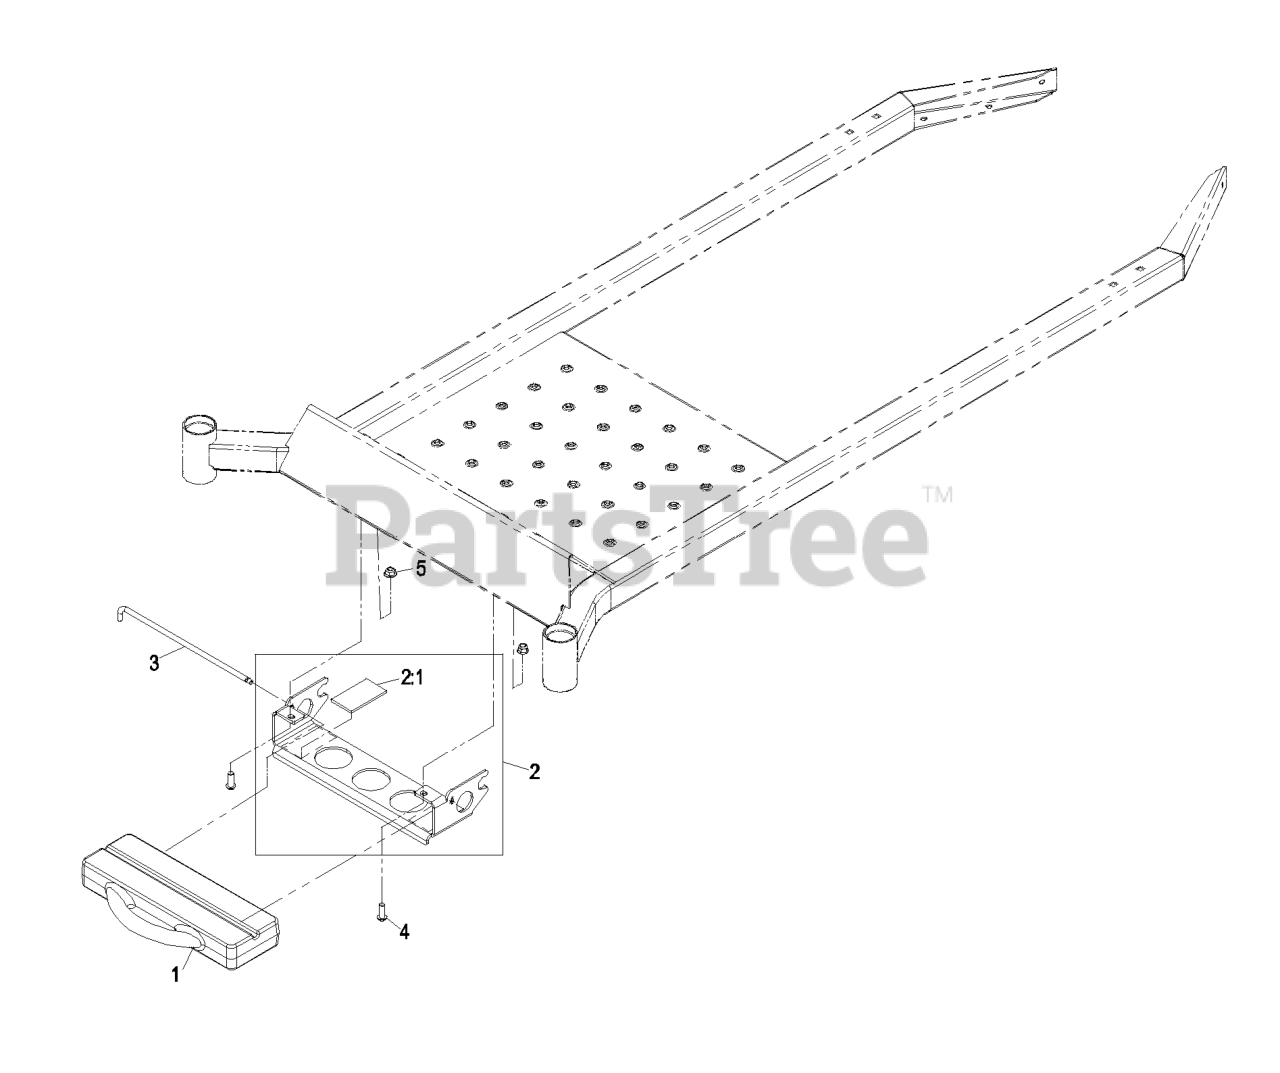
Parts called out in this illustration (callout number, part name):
2	BRACKET ASM
2:1	CUSHION-RUBBER
3	PIN-WEIGHT
4	SCREW-HSBH
5	NUT-HF, NI
